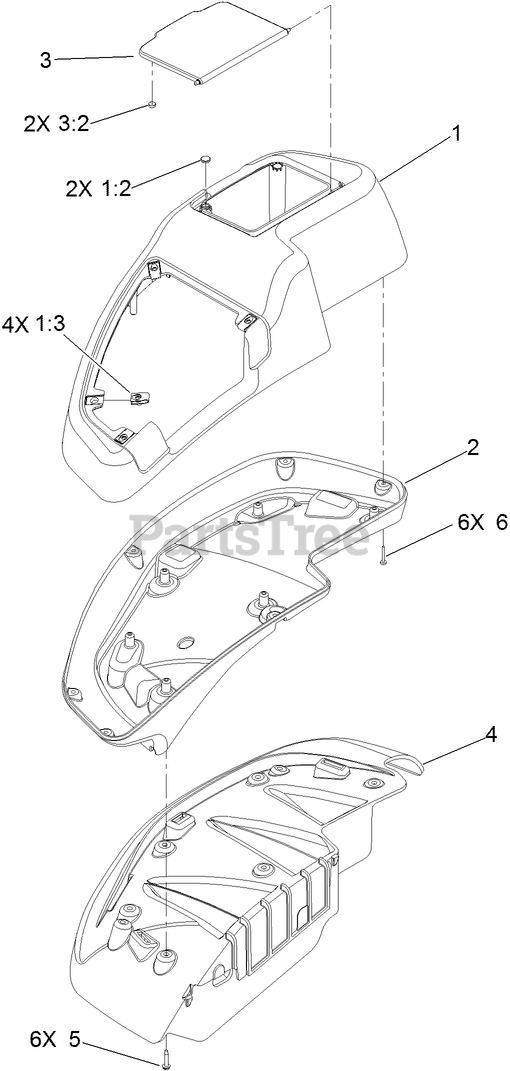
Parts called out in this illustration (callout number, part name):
1	RH WIDE TOP CONSOLE ASM
2	CONSOLE-LOWER, RH WIDE
3	WIDE LID ASM
3:2	MAGNET
4	FENDER-WIDE, RH
5	SCREW-THREAD FORMING
6	SCREW-PPH
